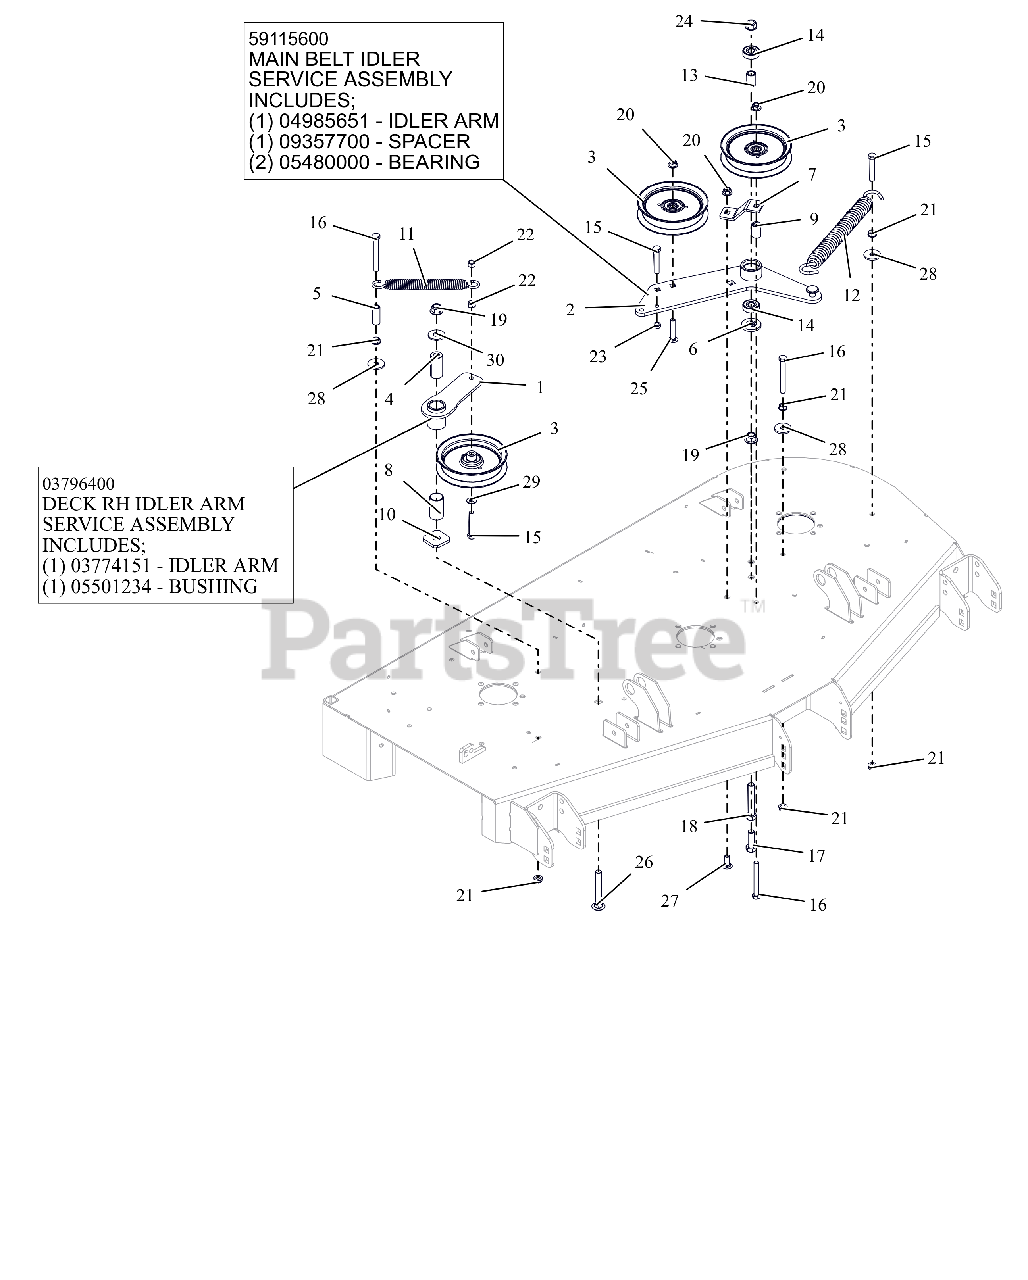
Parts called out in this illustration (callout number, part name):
1	WMT, IDLER ARM - BLACK
1	ASM, IDLER ARM (DECK)
2	DECK PTO IDLER ARM WLDMT - BLK
2	ASSEMBLY, MAIN BELT IDLER
3	IDLER, FLAT 5.00"
4	BSHG, SPCR .502X.997X2.03 PM
5	SPACER, .375IDX.625ODX1.66 PM
6	SPACER, IDLER ARM
7	PTO FIXED IDLER MTG BRKT -RED
8	BSHG, 1.00X1.125X1.937
9	BUSHING, SLV .380X.750X1.190
10	WSHR-FLT .640X1.75X.250
11	SPRING, EXTENSION
12	SPRING, EXTENSION
13	SPACER .510 X .75 X 1.1485
14	BRG-BALL .500X1.38X.437
15	BLT,HEX .38-16X2.25 G5 ZCC
16	BLT, HEX .38-16X3.25 G5 ZCC
17	BLT,HEX .50-13X1.50 G5 ZCC
18	BLT, HEX .50-13X3.00 G5 ZCC
19	NUT,NYL-FLG .50-13 GF ZCC
20	NUT,NYL-FLG .38-16 GF ZCC
21	NUT, SPNLK-FLG .38-16 G5 ZCC
22	NUT-LK-CTR .38-16 ZC120
23	NUT-JAM .375-16 G2 ZCC
24	NUT-LK-CTR-FLG .500-13 GG ZCC
25	BLT,RHSSN.375-16X2.00 G5 ZCC
26	BLT, RHSN .50-13X3.50 G5 ZCC
27	BLT,RHSSN .38-16X1.00 G5 ZCC
28	WSHR,FLT .406X1.375X.135 ZCC
29	WSHR,FLT .406X.812X.065 ZCC
30	WSHR,FLT .563X1.375X.109 ZCC
